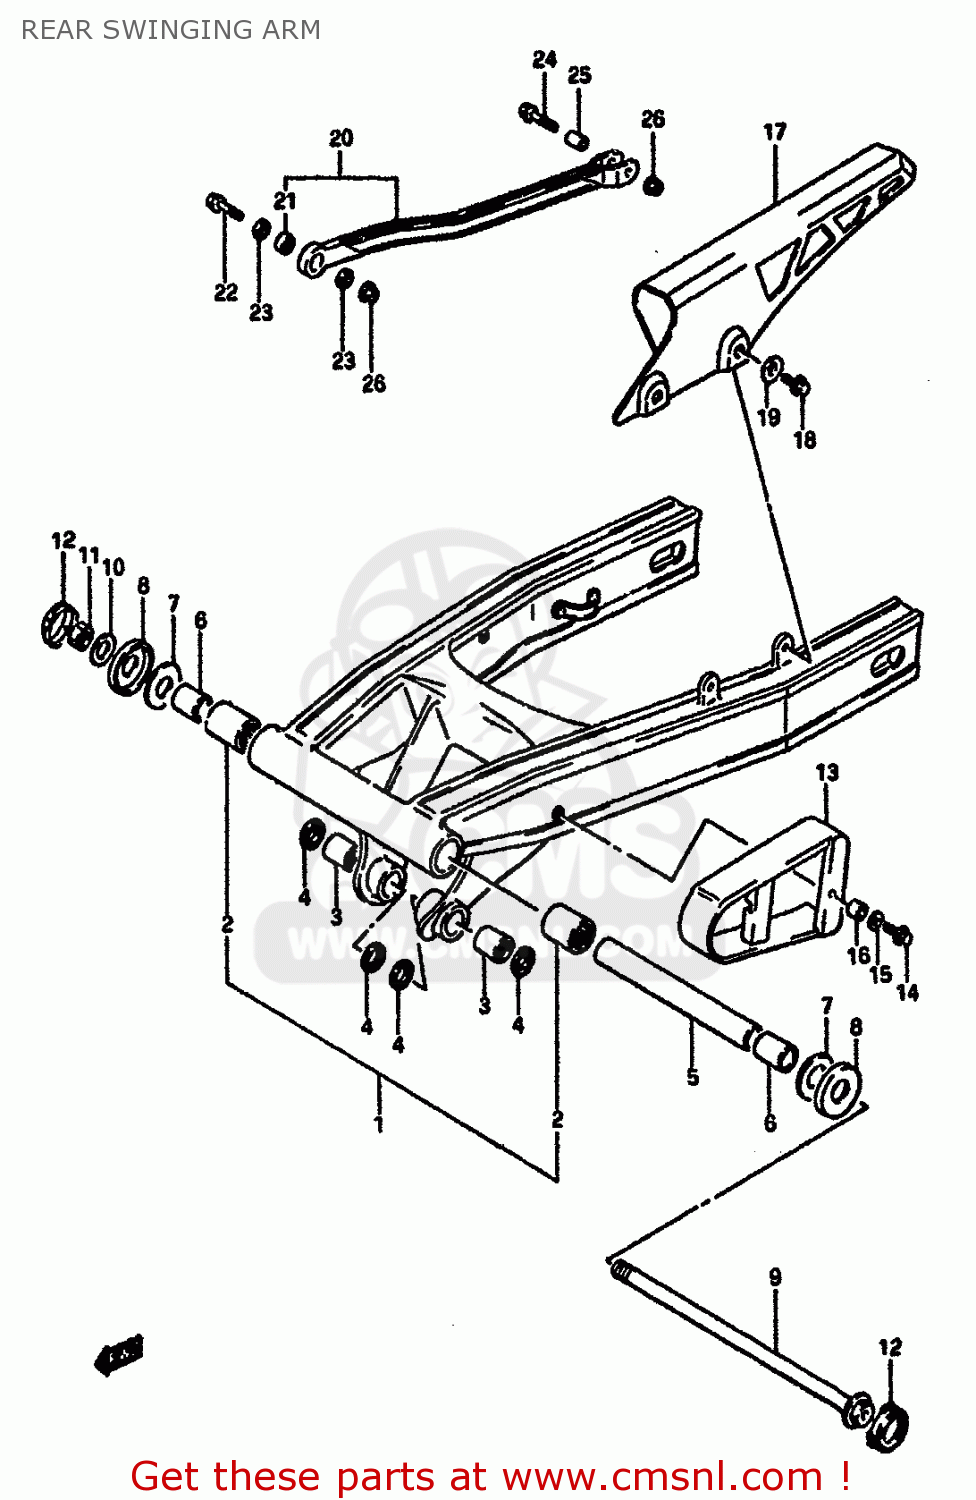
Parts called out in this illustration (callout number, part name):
1	SWING ARM ASSEMBLY,REAR
2	BEARING(22X29X25)
3	ROLLER BEARING (17X24X25))
4	SPACER,REAR CUSHION ROD
5	SPACER,RR SWGARM PIVOT CTR
6	SPACER,RR SWGARM PIVOT BEARING
7	WASHER
8	COVER,RR SWGARM DUST SEAL
9	SHAFT,REAR SWING ARM
10	WASHER(14X27X3)
11	NUT
12	CAP,SWINGINGARM PIVOT
13	BUFFER,CHAIN TOUCH DEFENSE
14	BOLT,M6X1X20
15	WASHER(6.5X16X1.2)
16	SPACER(6.5X8.5X5.8)
17	CASE,CHAIN
18	BOLT
19	WASHER
20	TORQUE LINK SET,REAR
21	SPHERICAL BEARING,TORQUE
22	BOLT(8X38)
23	24
24	BOLT(8X35)
25	SPACER,RR TORQUE LINK RR
26	NUT
